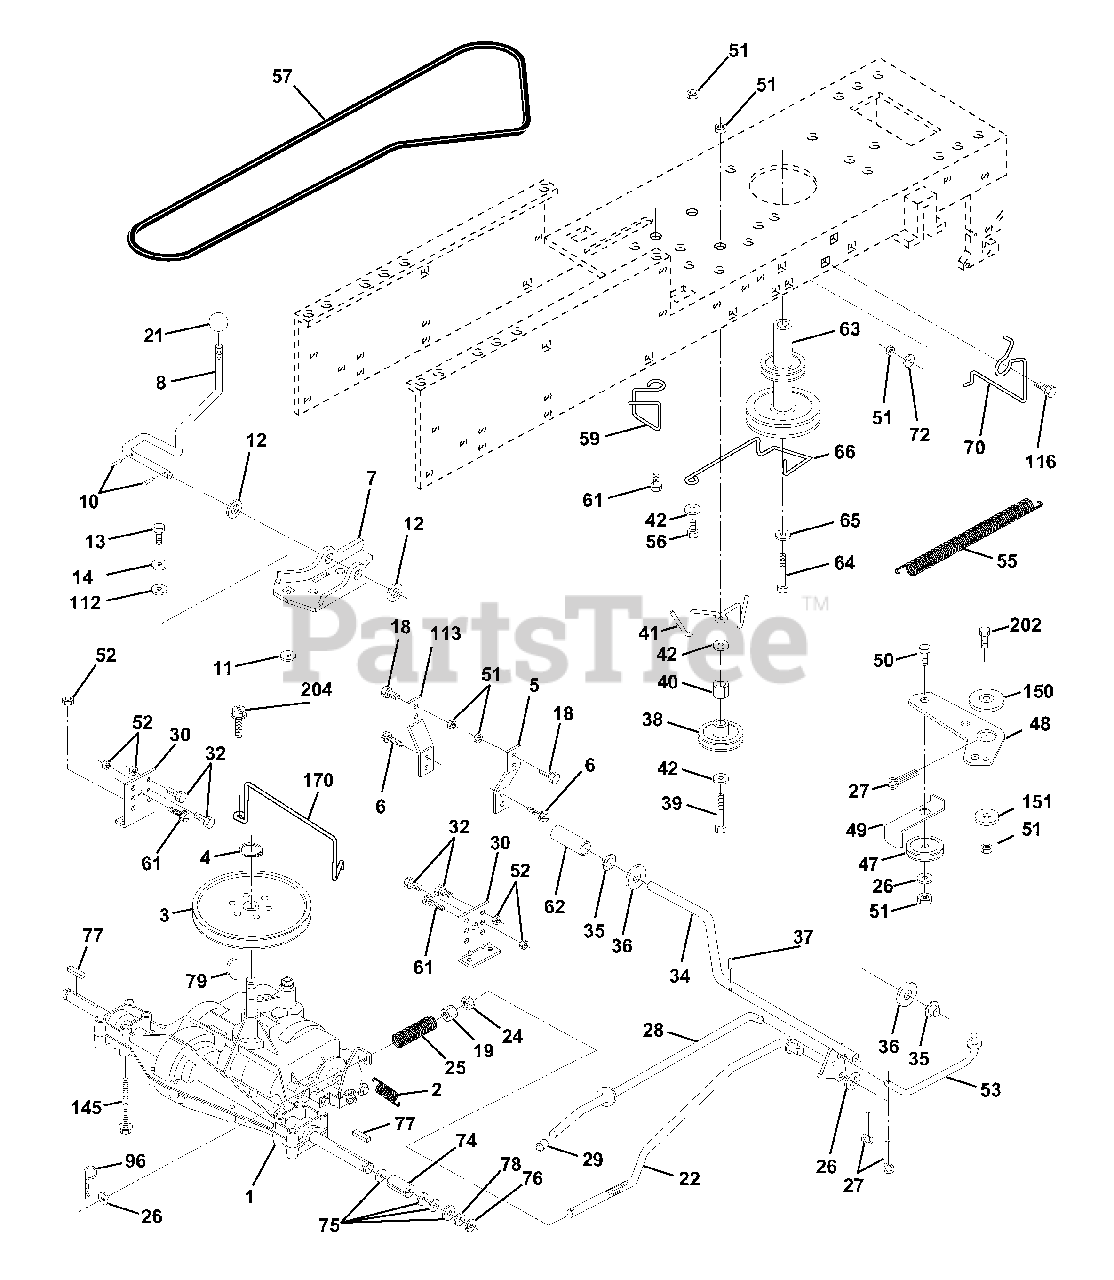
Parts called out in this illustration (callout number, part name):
2	Spring Extension Brake
3	Pulley Transaxle 18" tires
4	Ring Retainer # 5100-62
5	Strap Torque Rh Pnt Blk
6	Screw 5/16-18 X 3/4
7	Bracket T/A Saddle Shift
8	Rod Shifter Black(dana)
10	Pin
11	Washer Plate Shf 388 Sq Hole
12	Washer 15/32 X 3/4 X 16ga
13	Bolt 1/4-28 UNF Gr. 8 W/Patch
14	Washer
18	Bolt Fin Hex 3/8-16 UNC x 1 Gr. 5
19	Nut
21	Knob Rd 1/2-13 Plstc Thds Blk
22	Rod Brake Lt
24	Nut
25	Spring Rod Brake 2 00 Zinc
26	Washer
27	Pin
28	Rod Brake Parking Lt/Yt
29	Cap Parking Brake
30	Bracket Transmission
32	Bolt
34	Shaft Asm Pedal Foot
35	Bearing Nylon Blk 629 Id
36	Washer
37	Roll Pin
38	Pulley Idler Flat
39	Bolt Rdhd 3/8-16 Unc x 2-3/4 Gr. 5
40	Spacer Split 395 X 59 Bzp
41	Keeper Belt Idler
42	Washer 13/32 X 13/16 X 12 Ga
47	Pulley Idler V Groove Plastic
48	Bellcrank Clutch
49	Retainer Belt Style Spring
50	Bolt
51	Nut
52	Nut
53	Link Clutch 7 66
55	Spring Return Clutch 6 75
56	Bolt
57	V-belt Ground Drive 95
59	Keeper Belt Chassis Span Ctr.
61	Screw 3/8-16x3/4
62	Cover Pedal Blk Round
63	Pulley Engine
64	Bolt, Hex 7/16-20 x 4 Grade 5
65	Washer, Lock, Hvy Hlcl Spring 7/16
66	Keeper Belt Engine Flproof
70	Guide Belt Dr Mower Rh
72	Washer 13/32 X 1-1/4 X 12 Ga
74	Spacer Axle
75	Washer 25/32 X 1 1/4 X 16 Ga
76	E Ring
77	Key Square 2 0 X 1845/ 1865
78	Washer 25/32 X 1 5/8 X 16ga
79	Key Woodruff
96	Retainer Spring 1"
112	Washer 9/32 X 3/4 X 10 Ga
113	Strap Torque Lh
116	Bolt, Rdhd Sqnk 3/8-16 x 1.25
145	Bolt Hex Flghd 5/16-18 x Gr. 5
150	Bushing Bellcrank
151	Washer 13/32 x 2 x 10 Ga.
170	Keeper Belt
202	Bolt Carr. Sh. 3/8-16 x 1-1/2 Gr. 5
204	Screw 5/16-18 x 1
